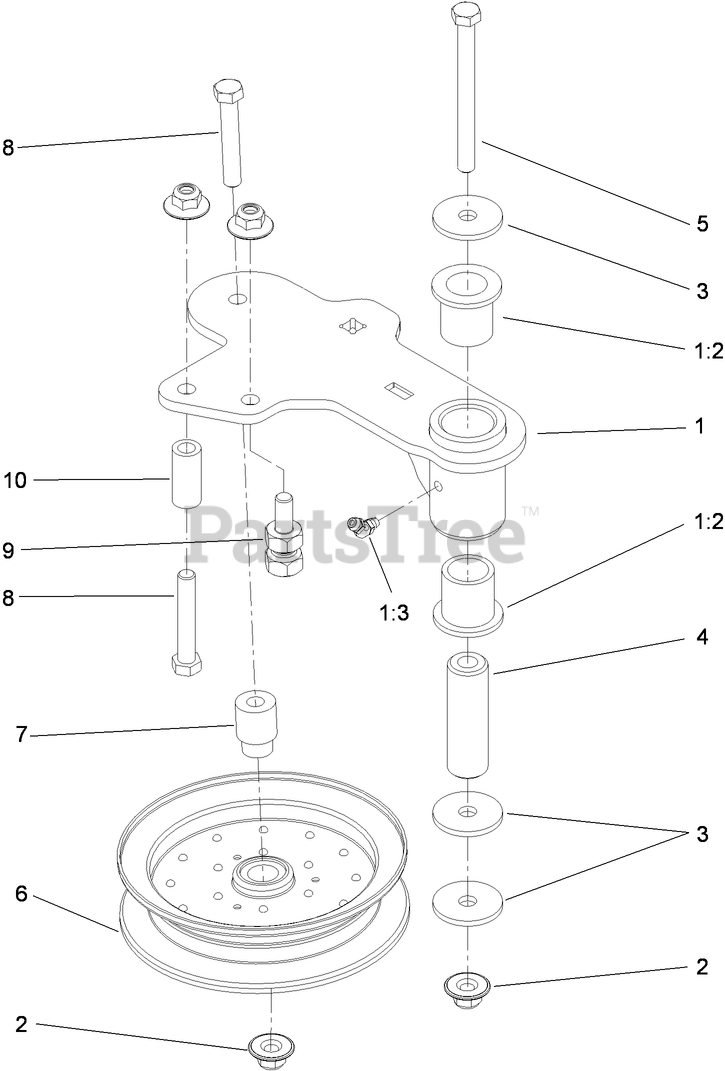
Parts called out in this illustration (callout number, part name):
1	IDLER ARM ASM
1:2	BEARING-FLANGED
1:3	FITTING-GREASE
2	NUT-FLANGE, NI
3	WASHER
4	SPACER-PLAIN
5	SCREW-HH
6	PULLEY-IDLER, FLANGED
7	MOUNT-PULLEY
8	SCREW-HH
9	ANCHOR-SPRING, SHORT
10	SPACER
